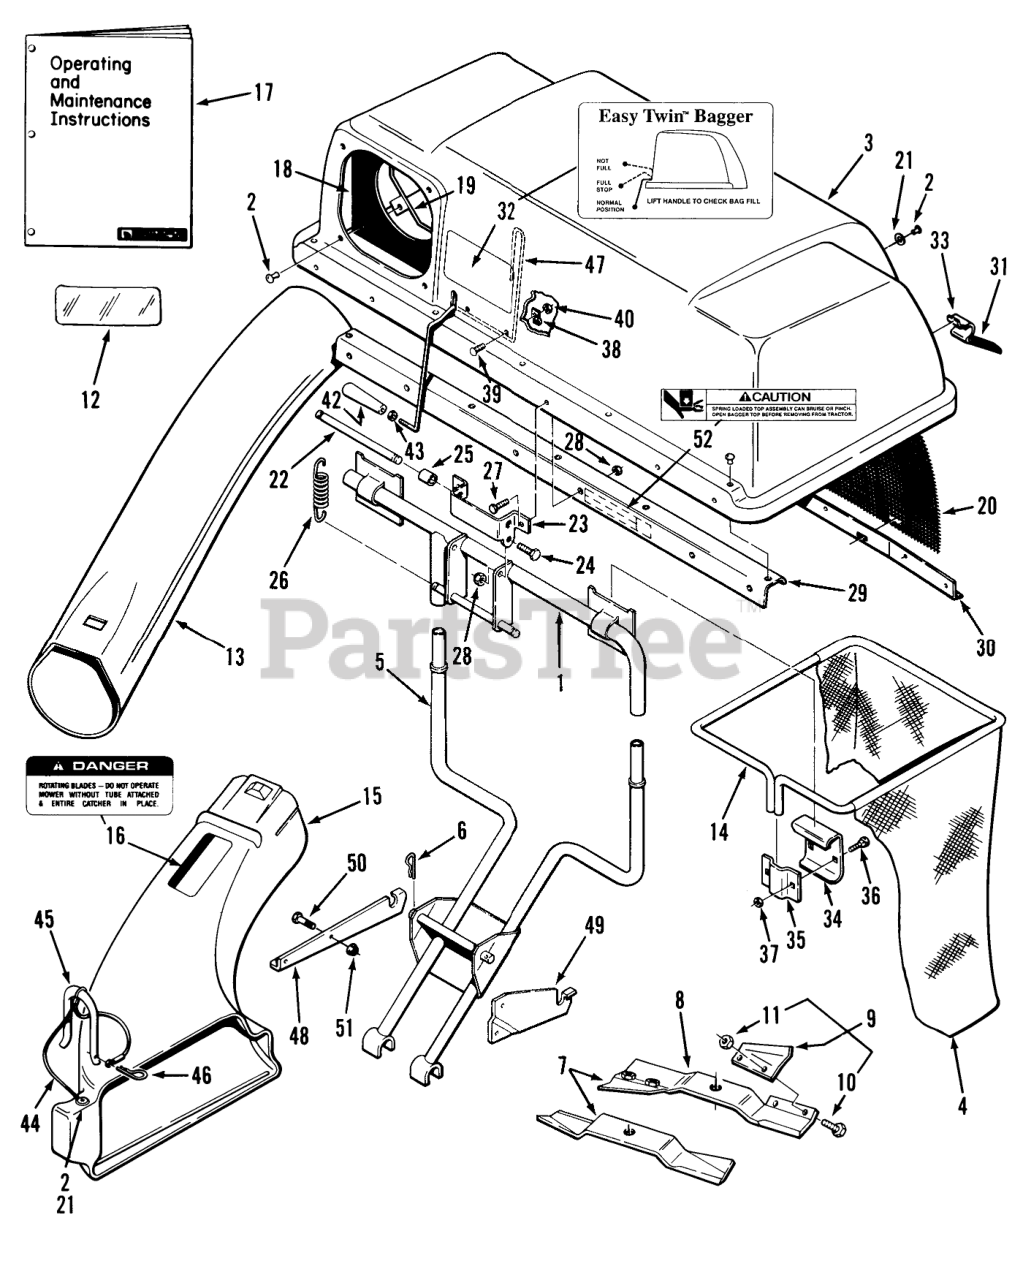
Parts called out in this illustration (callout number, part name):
2	RIVET-BLIND
6	Hairpin
7	KIT-BLADE (SERVICE)
8	ASS'Y-HI LIFT BLADE
9	S/A 37 LIFT TAB KIT
10	BOLT 5/16-18X5/8
11	NUT-HEX
12	DECAL-OVERLAY
13	CHUTE-BAGGER (L)
16	DECAL-DANGER
17	Operating and Maintenance Instructions
19	CLAMP-SEAL
20	SCREEN-BAGGER
22	PIN-SPRING
26	SPRING-EXTENSION
42	HANDLE-TAPERED
44	LANYARD-ELBOW LATCH
45	LATCH-ELBOW
46	Hairpin Cotter
47	FEELER-FILL, BAG
